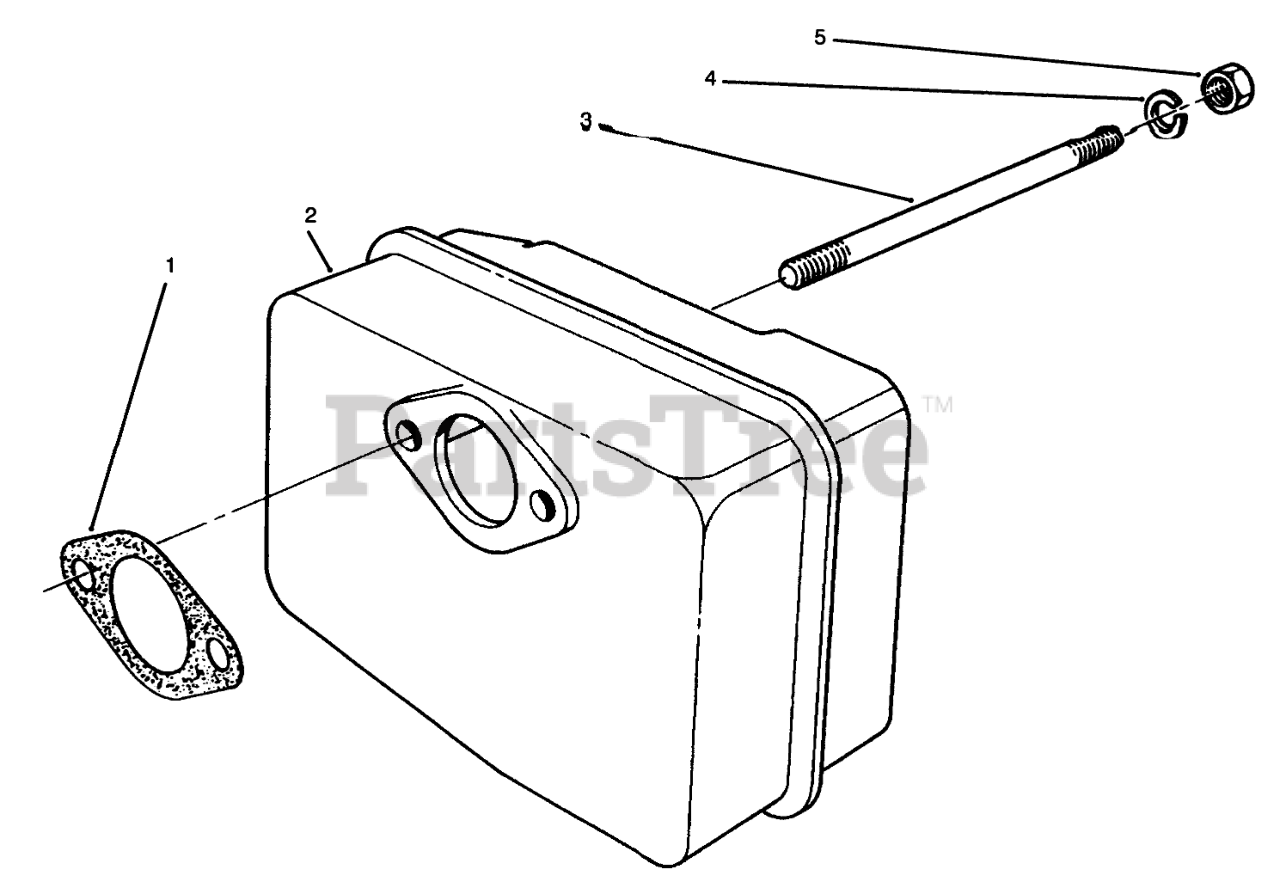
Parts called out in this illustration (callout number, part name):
1	GASKET
2	MUFFLER
4	WASHER-LOCK
